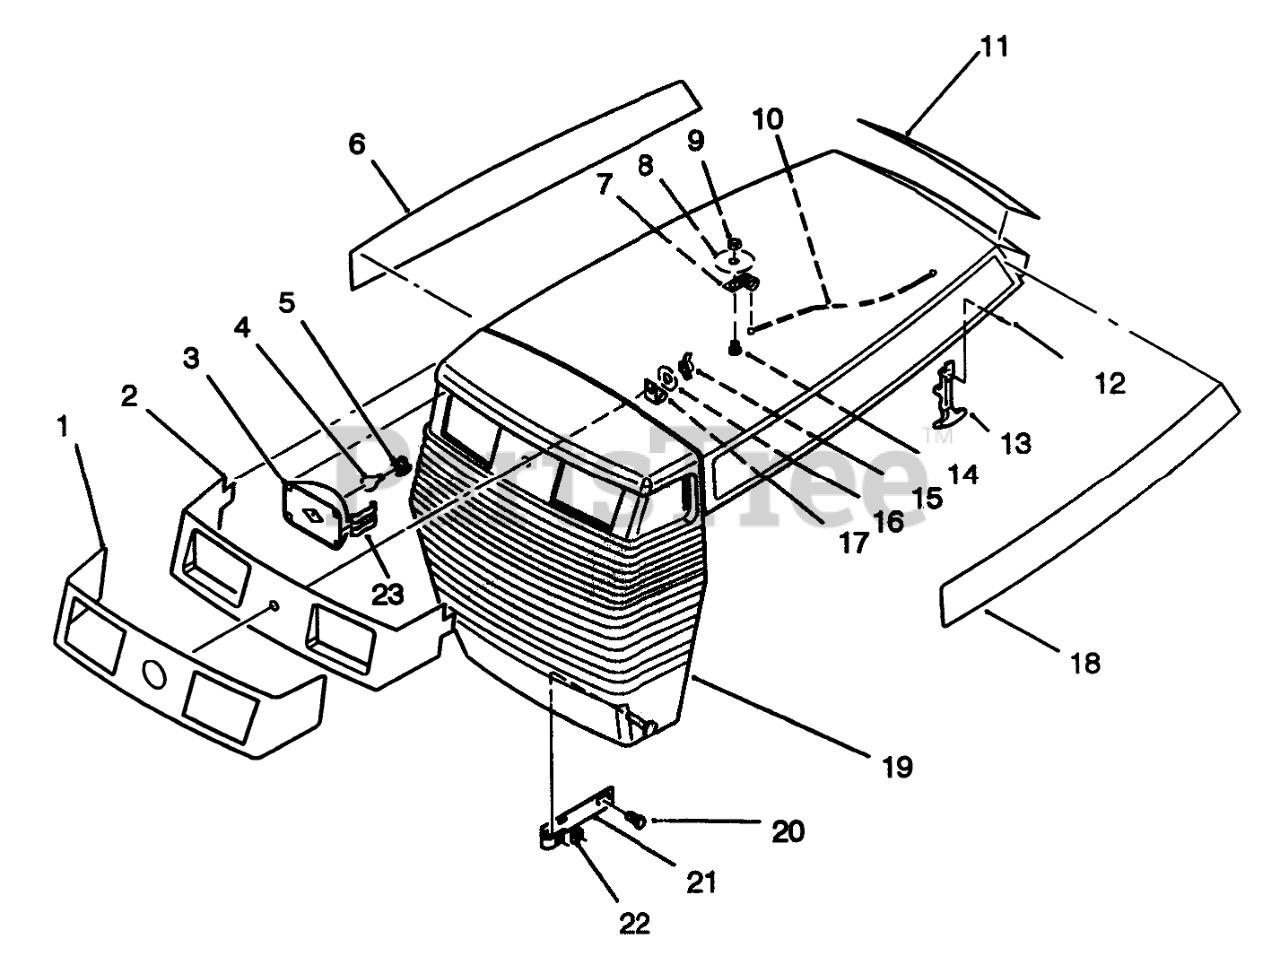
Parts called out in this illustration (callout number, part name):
1	DECAL-FRONT HOOD
2	LIGHT-BAR BLACK
3	LIGHT POD
4	BULB
5	SOCKET-HEADLIGHT
6	DECAL HOOD RH
7	CLEVIS
8	WASHER-BACKING
9	Nut
10	CABLE-ASS'Y
11	Decal-Hood Rear
12	RIVET-POP
13	HANDLE ASM
14	SCREW
15	WING NUT
16	WASHER
17	J-CLIP
18	DECAL-HOOD L.H. 246H
19	Hood
20	Screw
21	BRKT-HOOD MTG L.H R
22	PUSH-NUT 5/16
23	RETAINER
